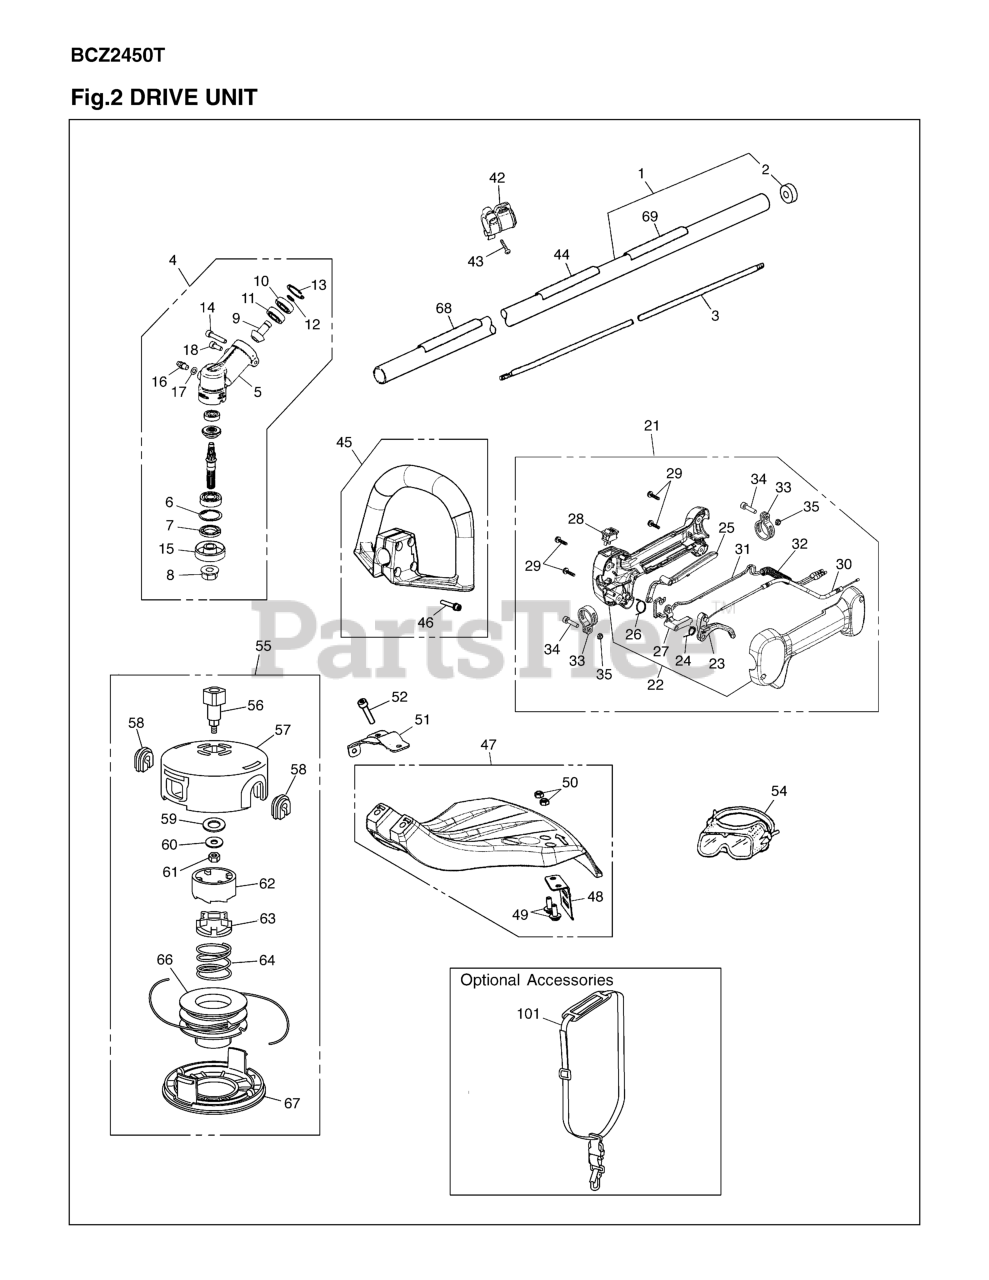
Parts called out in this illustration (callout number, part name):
1	PIPE COMP.
4	GEAR CASE ASSY
5	GEAR CASE
6	RING,SNAP M26x1.
7	SEAL, OIL(RPLS 3
11	BEARING (RPLS 06
12	SNAP RING
13	RING, SNAP, M24
14	BOLT, TORX
15	HOLDER-A
16	FITTING, GREASE
17	WASHER, M6 x .8
18	BOLT, TORX
21	GRIP-A
22	GRIP, HALF SET
23	LEVER, THROTTLE
24	SPRING, THROTTLE
25	LEVER SAFETY
26	SPRING
27	LEVER, JOINT
31	CORD - C
34	BOLT (RPLS 28501
35	NUT
42	HANGER COMP.
44	PLATE, NAME
45	HANDLE ASSY. (RP
47	GUARD ASSY
49	SCREW
52	BOLT, TORX
54	GOGGLExxx (RPLS
55	TAP HEAD COMPLET
56	SHAFT BOLT
57	CASE
58	EYELET KIT (2/ba
59	FLAT WASHER
60	FLAT WASHER
61	LOCK NUT
62	CAM FOLLOWER
63	INNER CAM
66	CORD HOLDER
67	COVER
68	LABEL CAUTON FOR
69	CAUTION LAEL
101	STRAP ASSY
